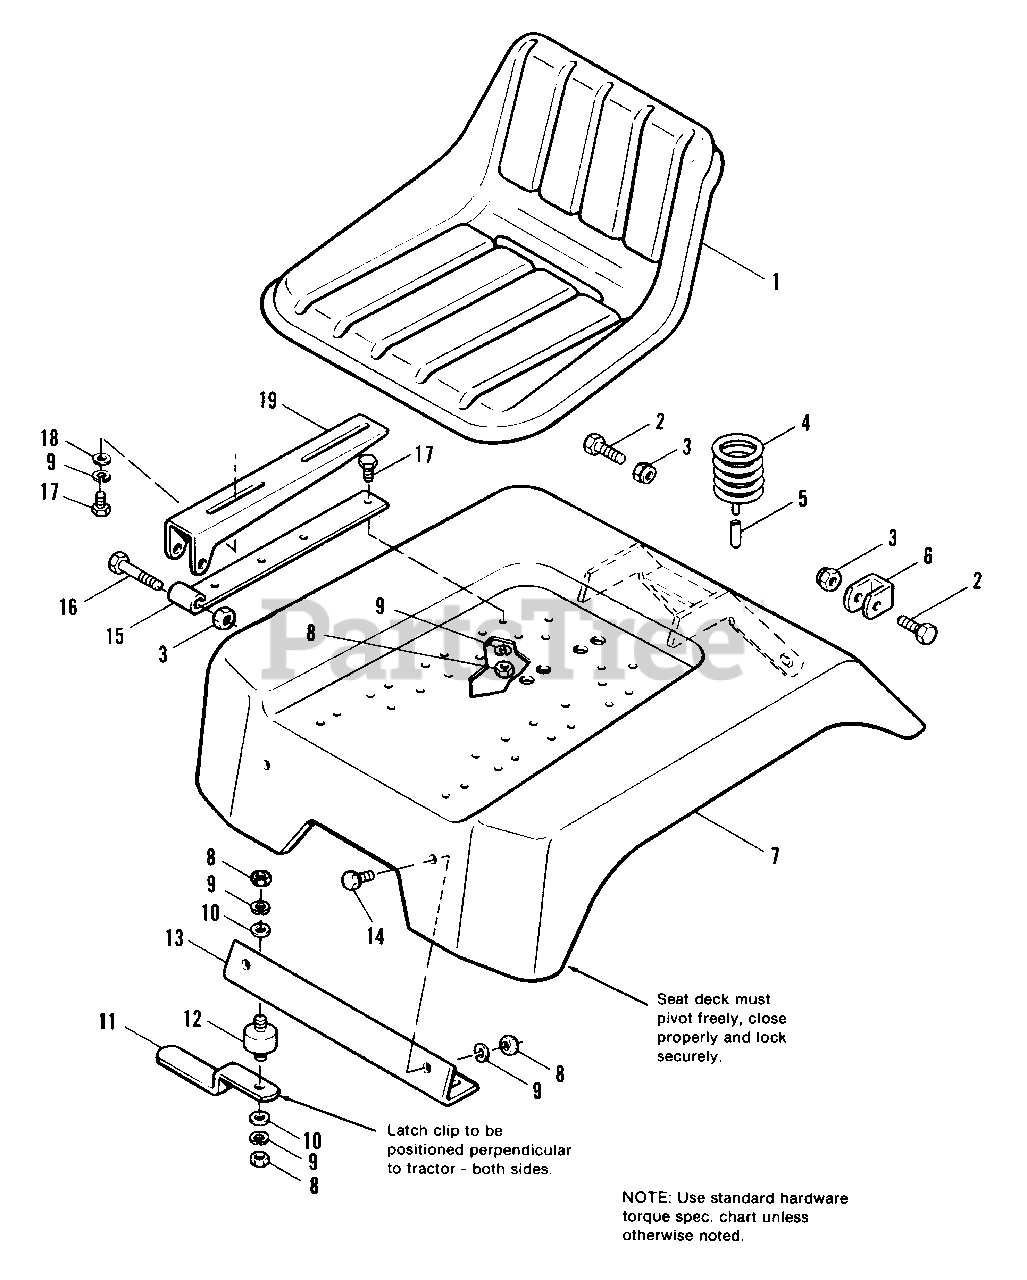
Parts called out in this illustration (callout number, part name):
1	SEAT ASSY., Contour
2	CAPSCREW, Hex Hd., 3/8-16 x 1-1/4
3	LOCKNUT, Hex, 3/8-16
4	SPRING, Seat
5	COVER, Wire
6	STOP, Seat Deck
7	DECK ASSY., Seat
8	NUT, Hex, Full, 5/16-18
9	LOCKWASHER, 5/16
10	WASHER, Plain, 1/4
12	CONNECTOR, Cushion
13	BRACKET, Seat Deck, Front
14	CAPSCREW, Hex Hd., 5/16-18 x 5/8
15	HINGE, Lower
16	CAPSCREW, Hex Hd., 3/8-16 x 2
17	CAPSCREW, Hex Hd., 5/16-18 x 3/4
18	WASHER, Plain, 5/16
19	HINGE, Upper
